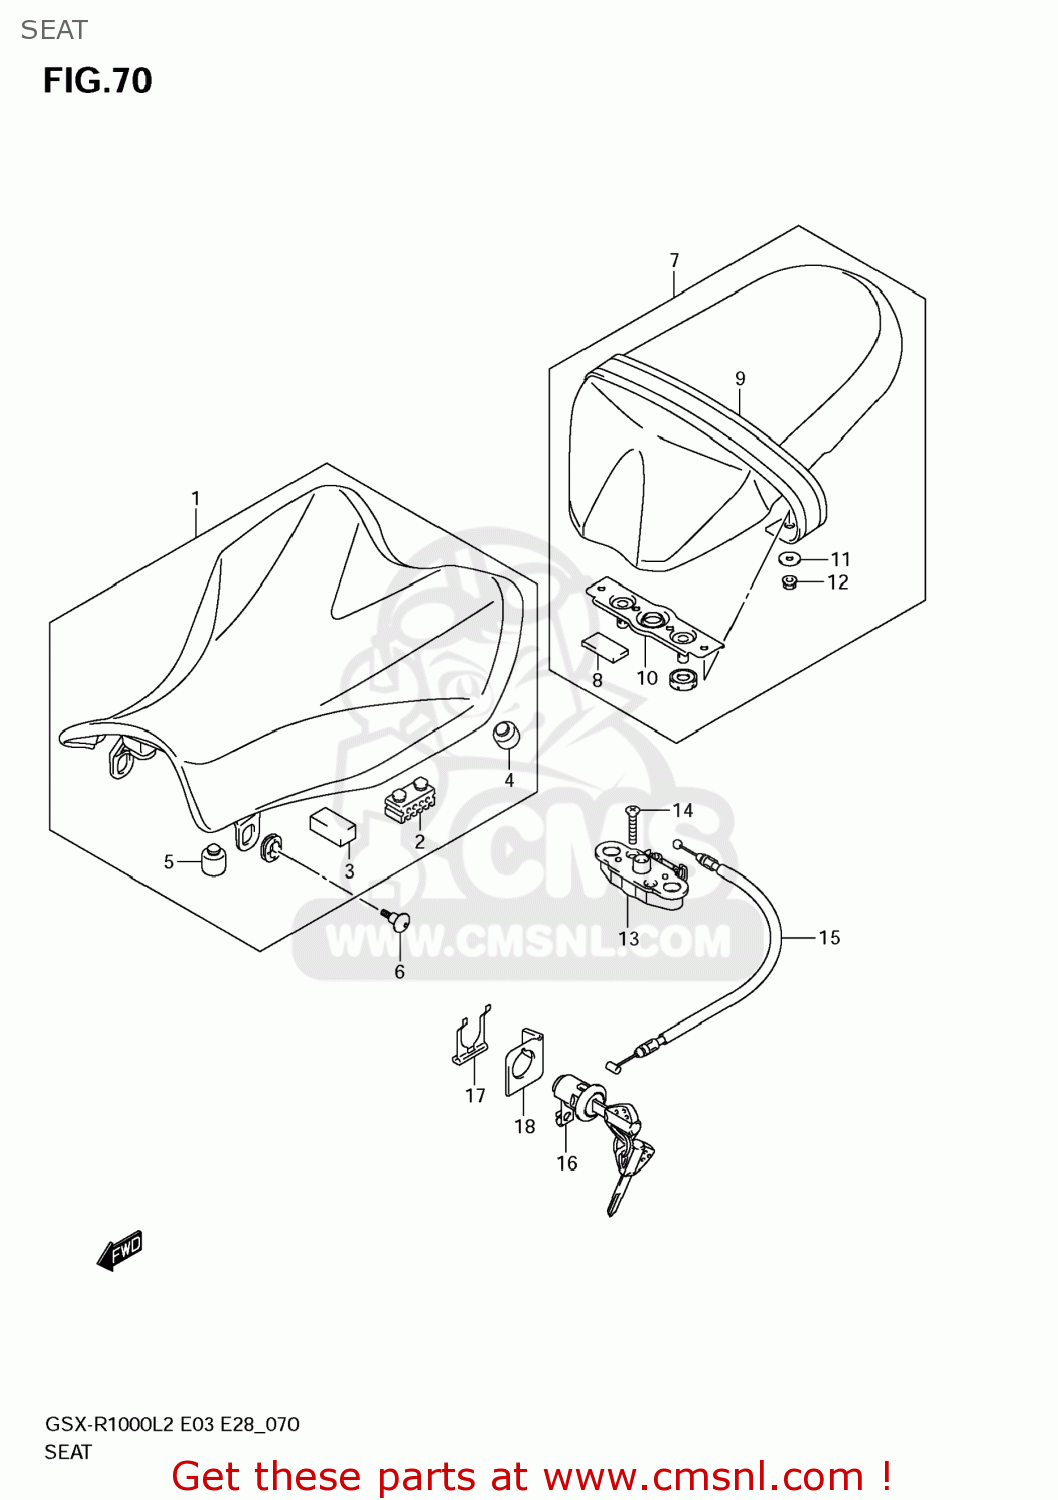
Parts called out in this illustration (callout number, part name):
1	SEAT ASSY
2	CUSHION,SIDE
3	CUSHION,FR(20X40X15)
4	CUSHION
5	CUSHION
6	BOLT(6X20)
7	SEAT ASSY,PILLION
8	CUSHION,FR(20X40X15)
9	BAND ASSY,SEAT(BLACK)
10	STRIKER
11	WASHER(6.5X20X1.6)
12	NUT
13	BRACKET,SEAT SUPPORT
14	SCREW
15	CABLE,SEAT LOCK
16	LOCK SET,SEAT
17	PLATE,SEAT LOCK ASSY
18	GUIDE,SEAT LOCK CABLE
